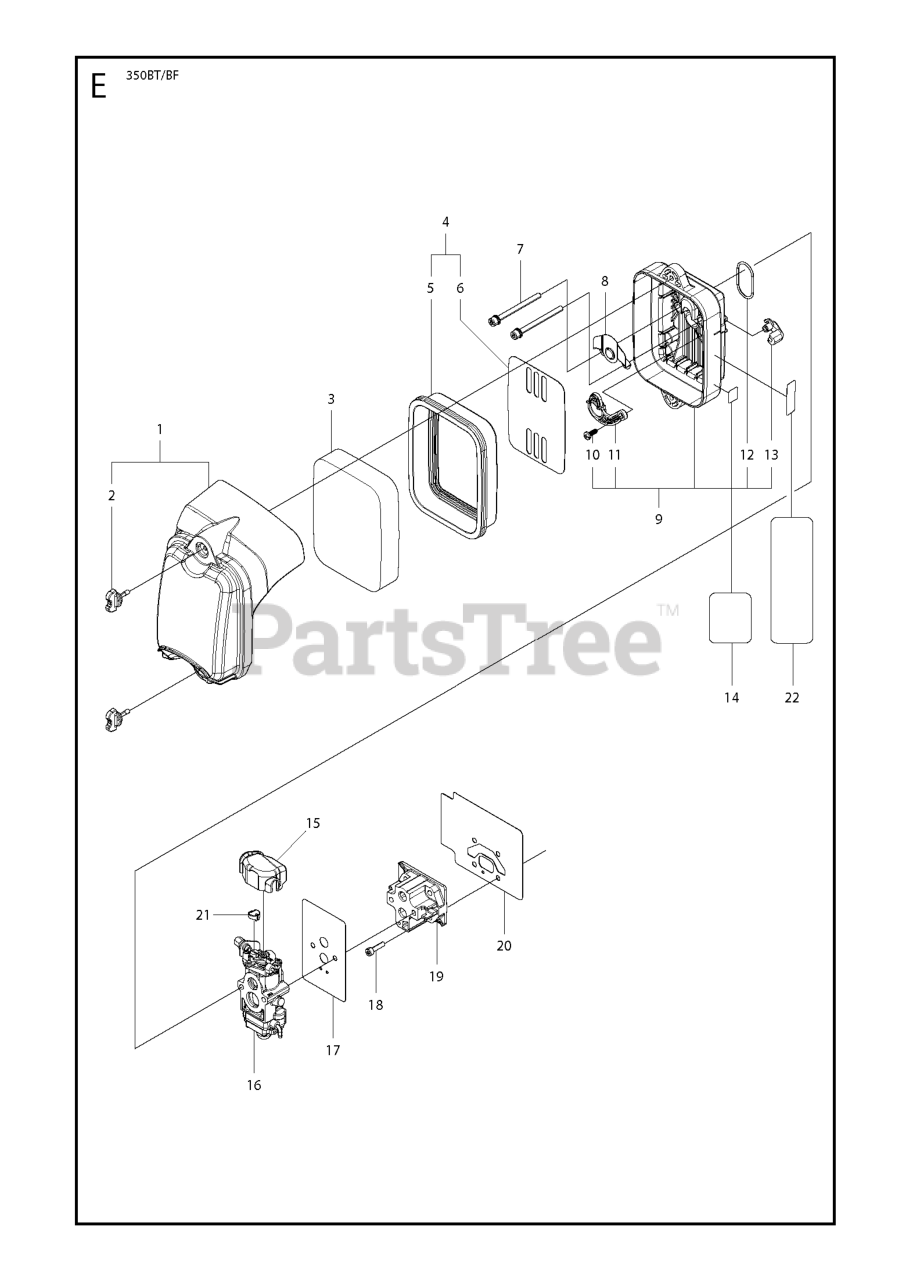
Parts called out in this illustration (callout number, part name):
3	AIR FILTER, ELEMENT
6	SCREEN
9	AIR FILTER HOLDER ASSY
16	CARBURETTOR
19	INSULATION
20	GASKET,INSULATOR
22	LABEL,CHOKE
